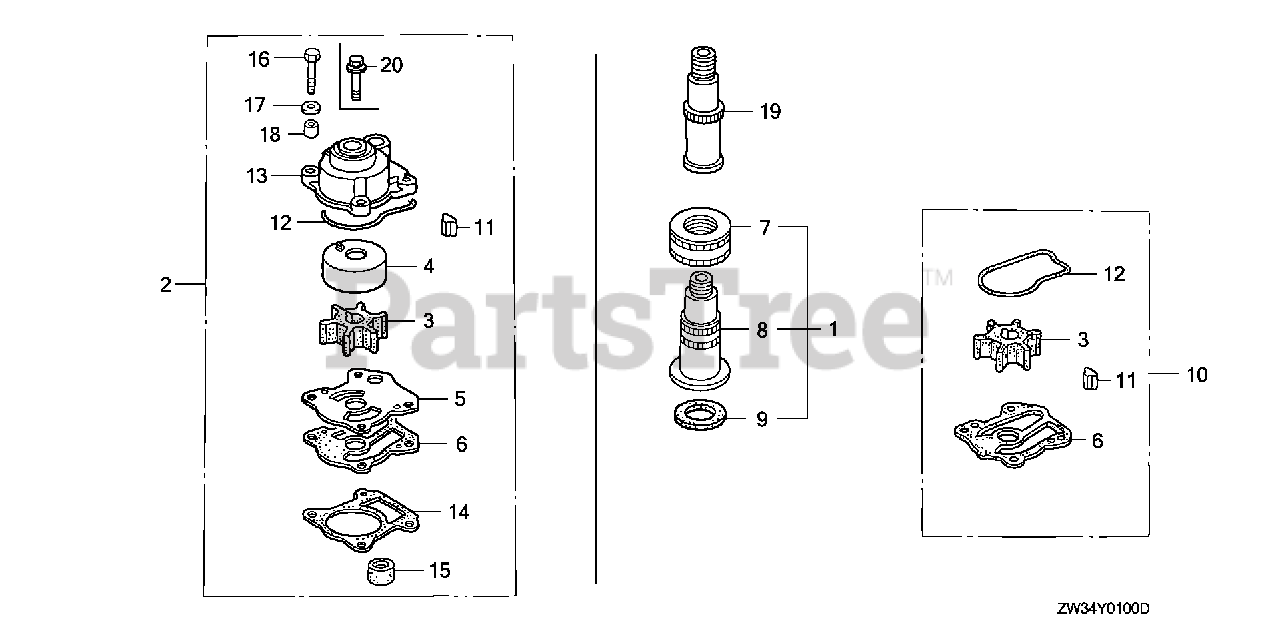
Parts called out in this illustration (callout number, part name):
1	JOINT KIT, WATER HOSE
2	PUMP KIT, IMPELLER (INCLUDES IMPELLER HOUSING)
3	IMPELLER, PUMP
4	LINER, PUMP
5	COVER, IMPELLER
6	GASKET B, IMPELLER
7	NUT, WATER MOUTH Use from Frame SN 1000929.
8	JOINT, WATER HOSE
9	SEAT, WATER MOUTH Use from Frame SN 1000929.
10	PUMP KIT, IMPELLER
11	KEY, WOODRUFF
12	O-RING, WATER PUMP
13	HOUSING, IMPELLER
14	GASKET, WATER PUMP
15	RING, WATER TUBE SEAL
16	BOLT, HEX. (6X40)
17	WASHER (6MM)
18	COLLAR, IMPELLER HOUSING
20	BOLT-WASHER (6X40)
